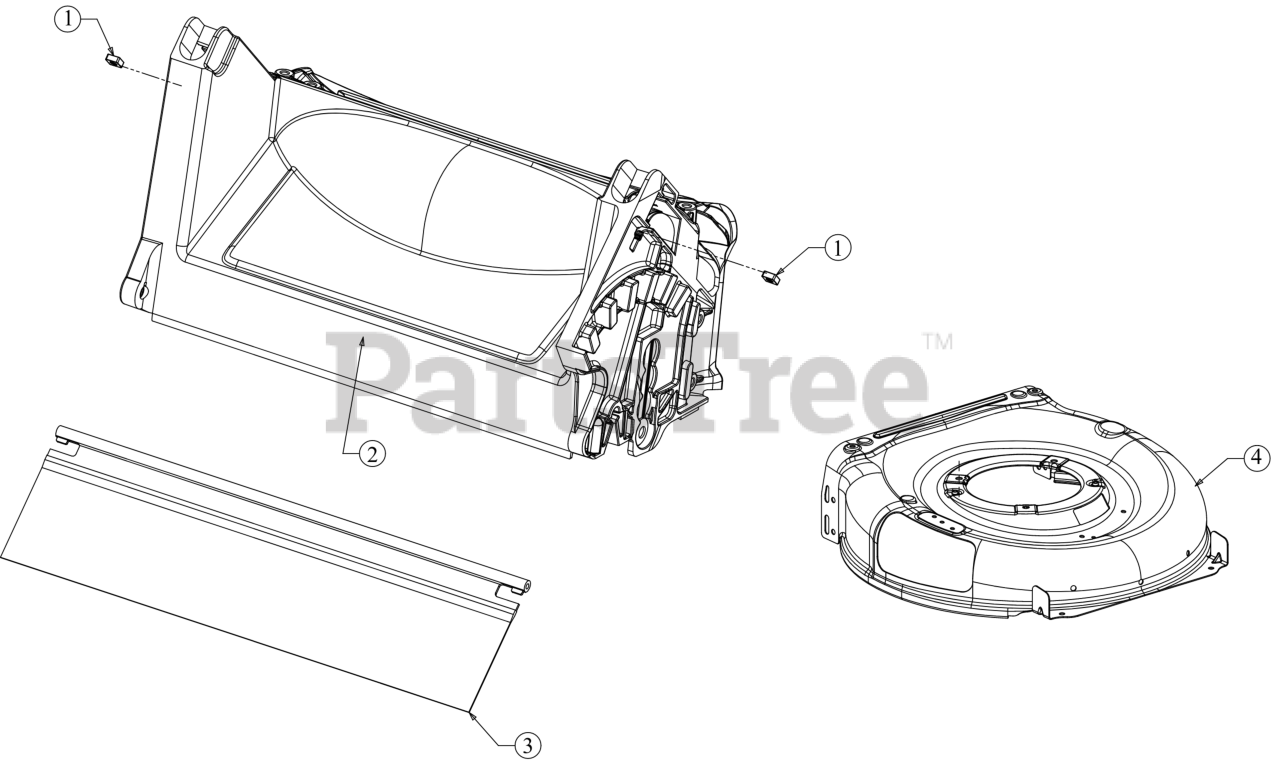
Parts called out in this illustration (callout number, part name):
1	SQUARE NUT 1/4-20
2	BAFFLE ASM-REAR 2 IN 1
3	TRAILSHIELD
